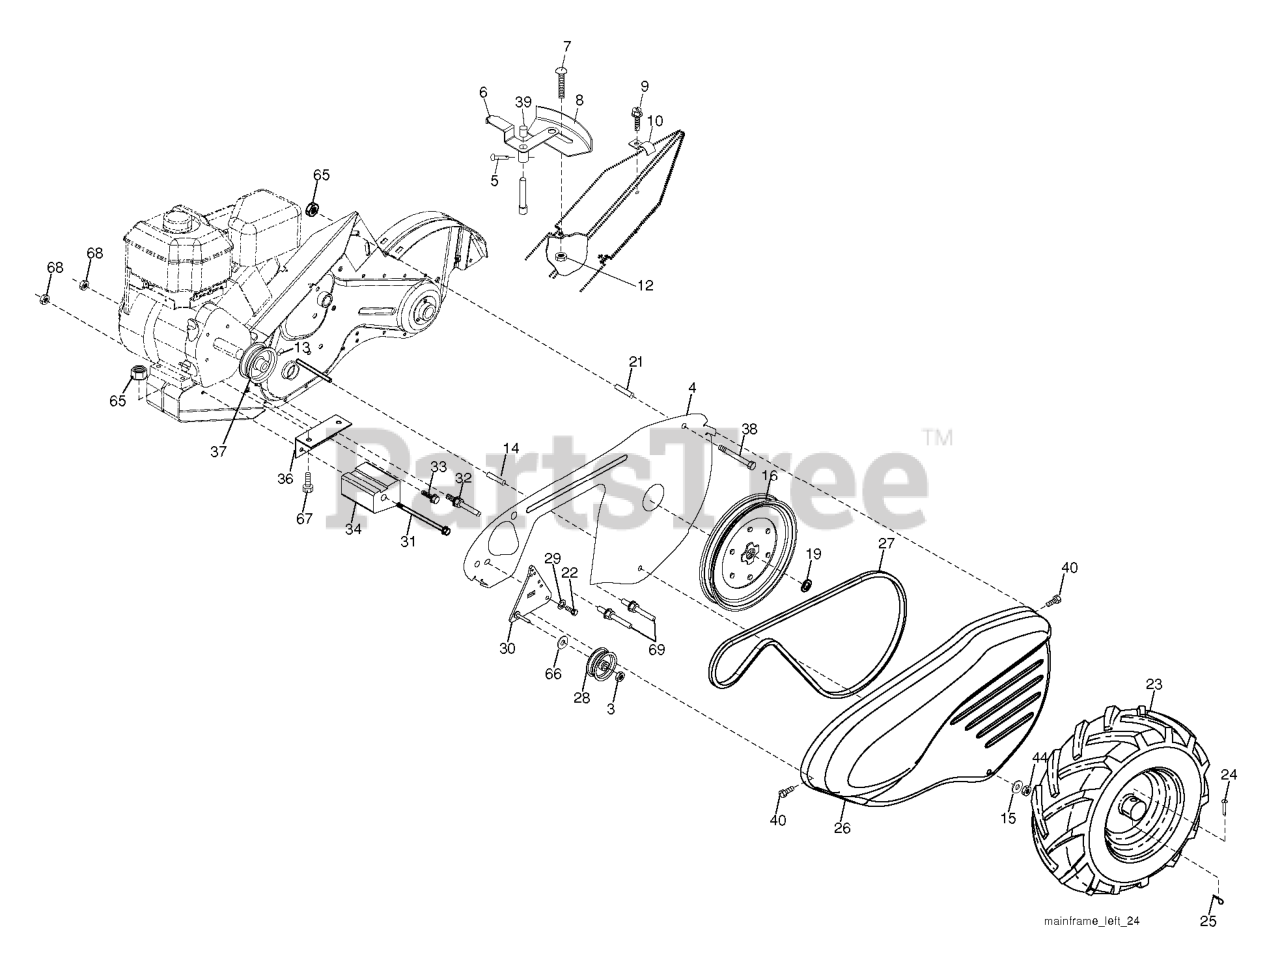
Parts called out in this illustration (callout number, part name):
3	NUT.HEX.3/8-16UNC
4	SHIELD.INNER.BELT.GUARD.RT
5	PIN.SPIROL.FLARED
6	LEVER.ASM.SHIFT.RED
8	RP.PANEL.SHIFT
9	TAPPING SCREW
10	CONDUIT.CLIP.PLATED
12	NUT
14	SPACER CRT
15	WASHER
16	SHEAVE, TRANSMISSION
19	RETAINING RING LT
21	SPACER-SPLIT.327 X .42
23	TIRE.13X5-6.CHEVRON.TILLER
24	RIVET,DRILLED
25	RETAINER M
26	GUARD.BELT.TILLER.ORANGE
27	V-BELT
28	PULLEY-IDLER TI
30	BRACKET.ASM.IDLER.BLACK
31	BOLT.FIN.HEX.3/8-16UNC
32	SHIFT ARM CRT
33	BOLT
34	COUNTERWEIGHT.LH.CRT
36	BRACKET LH CRT
37	RP.ENGINE PULLEY
38	BOLT
39	CAP.PLUNGER.BLACK
40	SCREW.HEX.WSH.SLT.#10-24X.50
44	NUT.71038.31-18.HEX.NYLOCK
65	LOCKNUT-FLANGE 5/16-18
66	WASHER
67	BOLT
69	KEEPER.BELT.ENGINE
